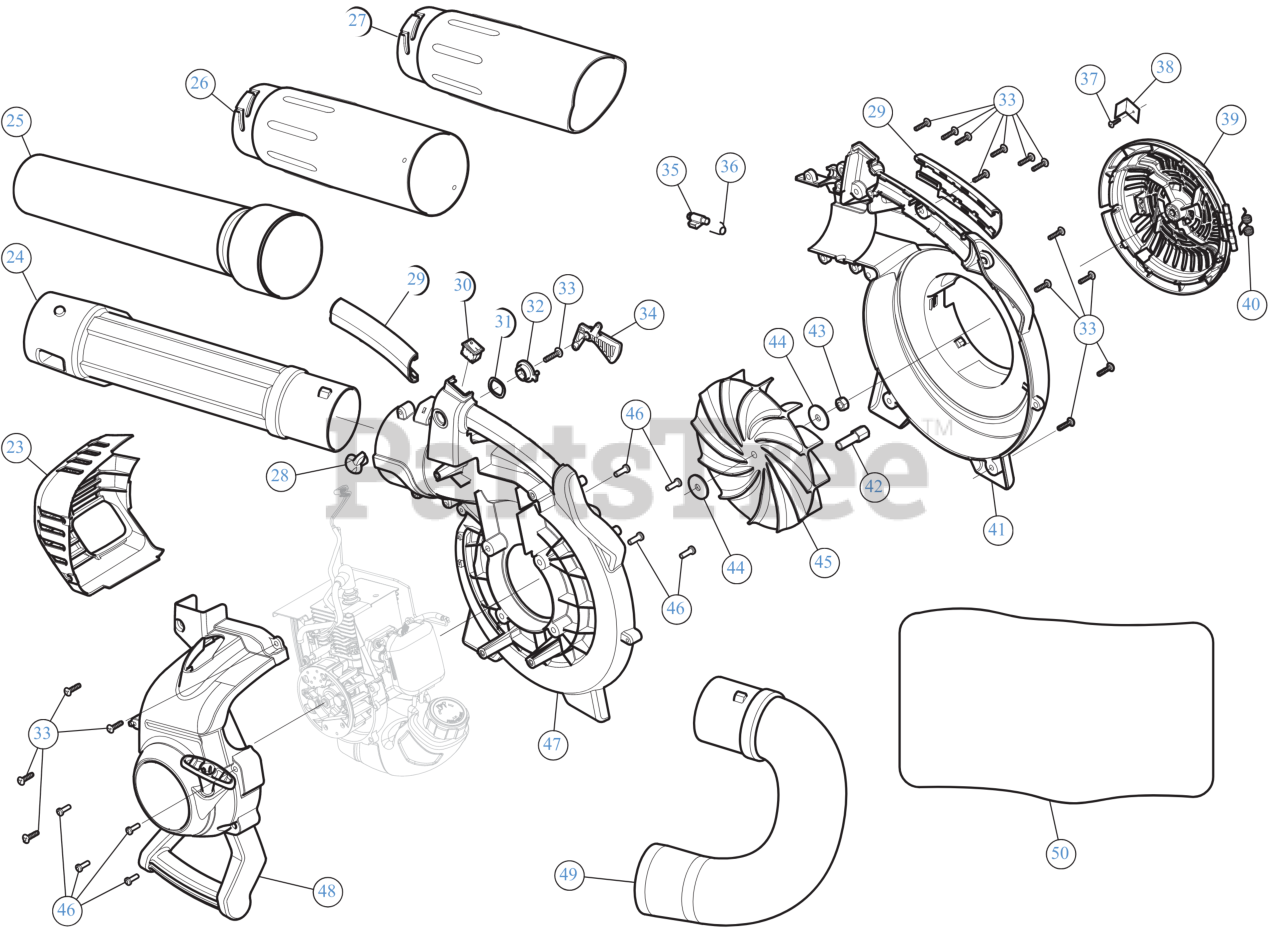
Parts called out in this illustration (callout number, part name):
23	MUFFLER COVER
24	UPPER TUBE
25	LOWER TUBE
26	UPPER VAC TUBE SCBLO
27	TUBE, LOWER VACUUM (ELEC BLWR-
28	TRIGGER LOCK OTR
29	ANDLE GRIP ASSEMBLY
30	SW, MOMENTARY ON/O
31	WASHER WAVEY
32	TRIGGER LOCK INR
33	SCREW 8-16 x 3/4
34	THROTTLE TRIGGER
35	LATCH TUBE
36	SPRING LATCH
37	SCREW-10-9 x .50
38	DOOR LOCK SC
39	INTAKE COVER
41	IMPELLER HOUSING OTR
42	ADAPTER STARTER
43	HEX NUT CENTER
44	WASHER FLAT
46	SCREW:10-32X.562:#8P
47	IMPELLER HOUSING INR
48	STARTER ASSEMBLY
49	ELBOW TUBE
50	VAC BAG SCBLO
